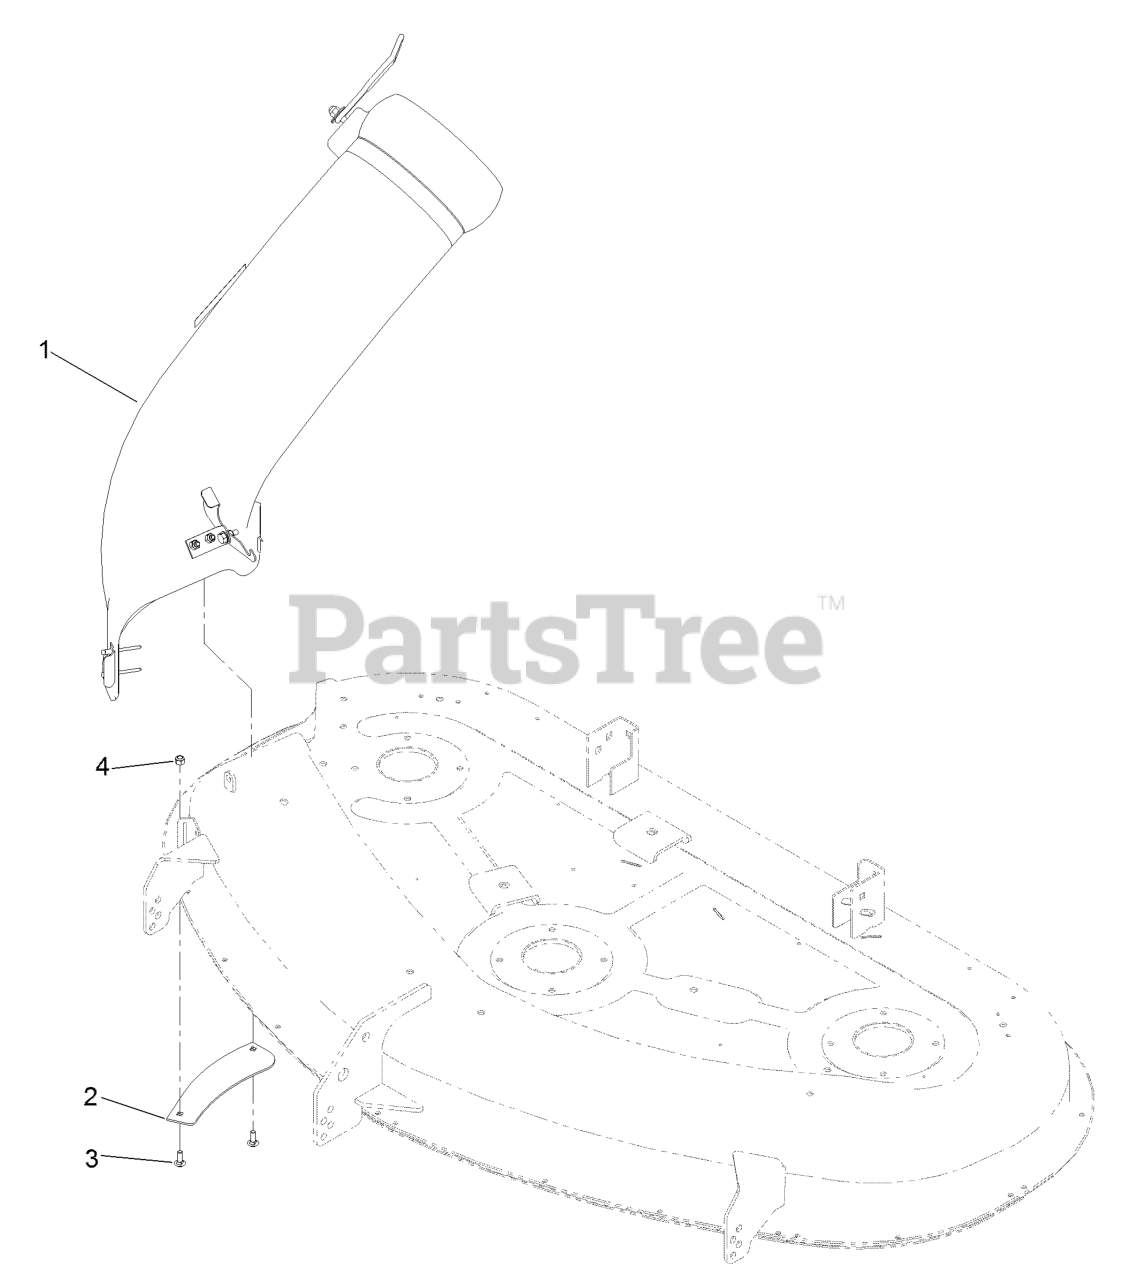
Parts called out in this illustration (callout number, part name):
1	50 INCH CHUTE ASM
2	BAFFLE-BLOWOUT
3	BOLT-CARR
4	NUT-LOCK, NI
